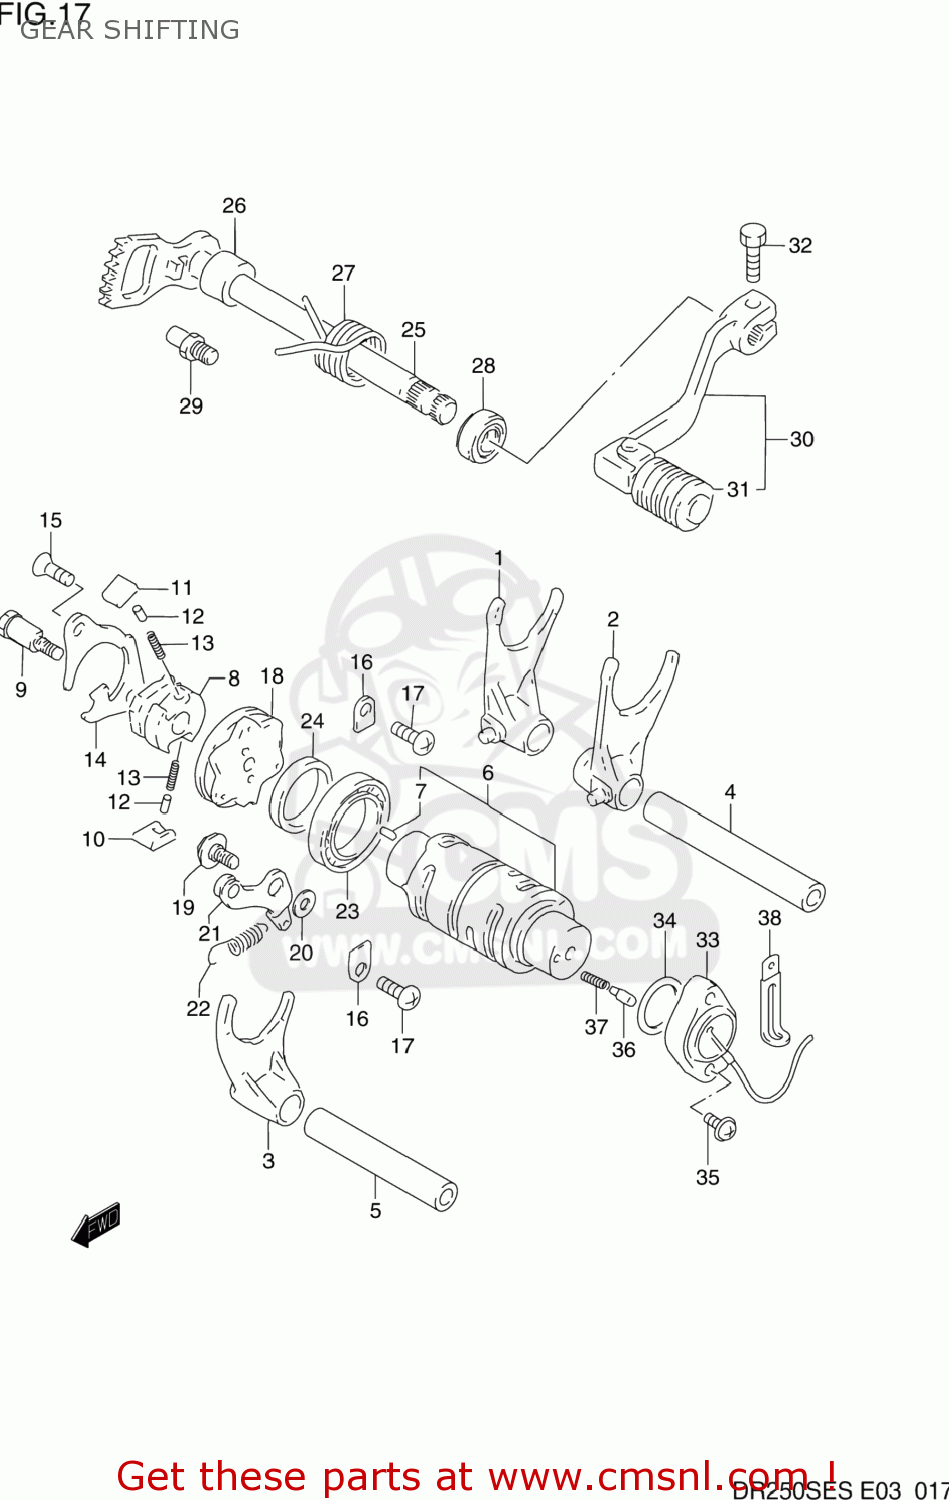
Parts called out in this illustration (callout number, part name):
1	FORK,GEAR SHIFT NO.1
2	FORK,GEAR SHIFT NO.2
3	FORK,GEAR SHIFT NO.3
4	SHAFT,GEAR SHIFT FORK
5	SHAFT,GEAR SHIFT FORK(L:70)
6	CAM,GEAR SHIFT
7	PIN
8	GEAR,GEARSHIFT CAM DRIVE
9	PIN,SHIFT CAM DRIVEN GEAR
10	PAWL,GEAR SHIFT NO.1
11	PAWL,GEAR SHIFT NO.2
12	PIN(5X8)
13	SPRING
14	LIFTER,GEAR SHIFT PAWL
15	SCREW
16	RETAINER
17	SCREW
18	PLATE,GEAR SHIFT CAM
19	BOLT(6X14.3)
20	WASHER
21	STOPPER,GEAR SHIFT CAM
22	SPRING
23	BEARING
24	WASHER(25X32X5.3)
25	SHAFT,GEAR SHIFT
26	SPACER(12X20X15.3)
27	SPRING
28	OIL SEAL
29	STOPPER,GEAR SHIFT ARM
30	LEVER ASSY,GEAR SHIFT
31	RUBBER,GEAR SHIFT PEDAL
32	BOLT
33	BASE ASSY,NEUTRAL SW TERMINAL
34	O RING(D:2.4,ID:26.2)
35	SCREW
36	PIN(5X15.5)
37	SPRING
38	CLAMP
